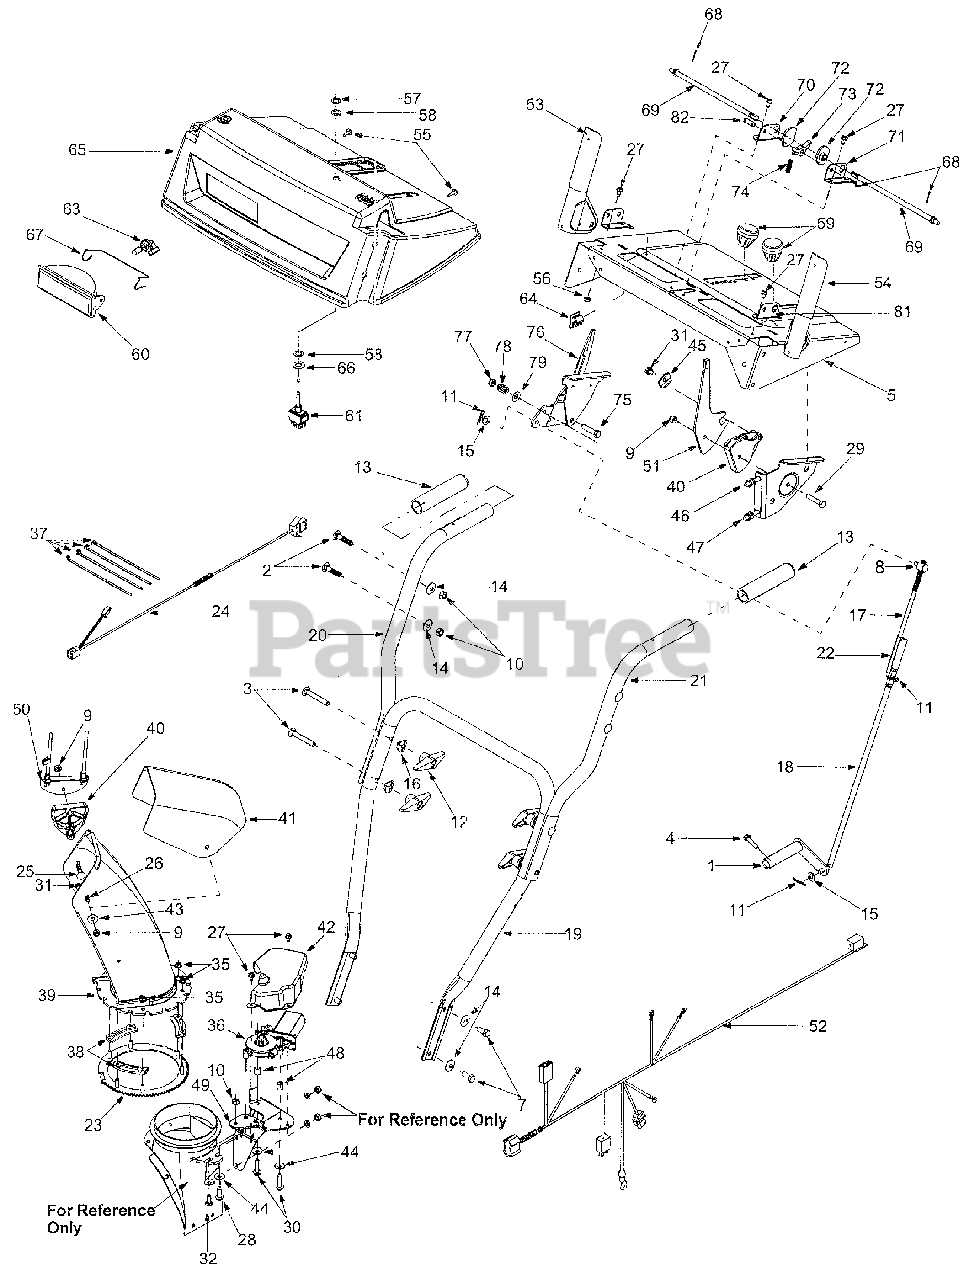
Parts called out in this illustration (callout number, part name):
2	Carriage Bolt 5/16-18 x 1.5"
3	Carriage Bolt 5/16-18 x 2.25"
4	TT Screw 114-20 x 1"
7	Hex Screw 5/16-18 x .75"
8	Ferrule
9	Hex Lock Nut 5/16-18
10	Hex Nut 5/16-18
14	Belleville Washer
16	Saddle Washer
17	Shift Rod: Upper
18	Shift Rod: Lower
23	Gear Assembly: Ring
24	Electric Harness: Lower
25	Carriage Bolt: 5/16-18 x 1.5"
26	Carriage Bolt: 5.16-18 x .750"
27	TT Screw: 1/4-20 x 0.5"
28	TT Screw: 5/16-18 x 1"
29	Hex Screw: 5/16-18 x 1.5"
30	TT Screw: 5/16-18 x 1.25"
31	Hex Screw AB:1/4-14 x 0.625"
32	Hex Screw: 5/16-18 x .75"
35	Hex Flange Lock Nut
36	Electric Motor: Chute Crank
38	Chute Flange Keeper
39	Lower Chute
40	Cable Guide: Chute: Tilt
41	Upper Chute
42	Motor Cover: Chute Rotation
44	Belleville Washer
45	Special Washer
46	Control Cable
47	Control Cable
52	Harness Assembly: Upper
53	Handle Assembly RH
54	Handle Assembly LH
55	Special Hex Screw
56	Hex Sems Nut: 1/4-20
58	Lock Ring: Toggle Switch
59	Shift Knob
60	Lamp Housing
61	Toggle Switch: Double Throw
63	Halogen Lamp: 50W, 12V
64	Mounting Clamp
65	Handle Panel
66	Flat Washer
67	Headlight Retainer
68	Cotter Pin .072 x 1.12
72	Cam Handle Lock
73	Handle Lock Pawl
74	Compression Spring: .36 x 1.0
75	Hex Cap Screw: 3/8-24 x 1.5
78	Comp. Spring: .39 x .6 x .88
